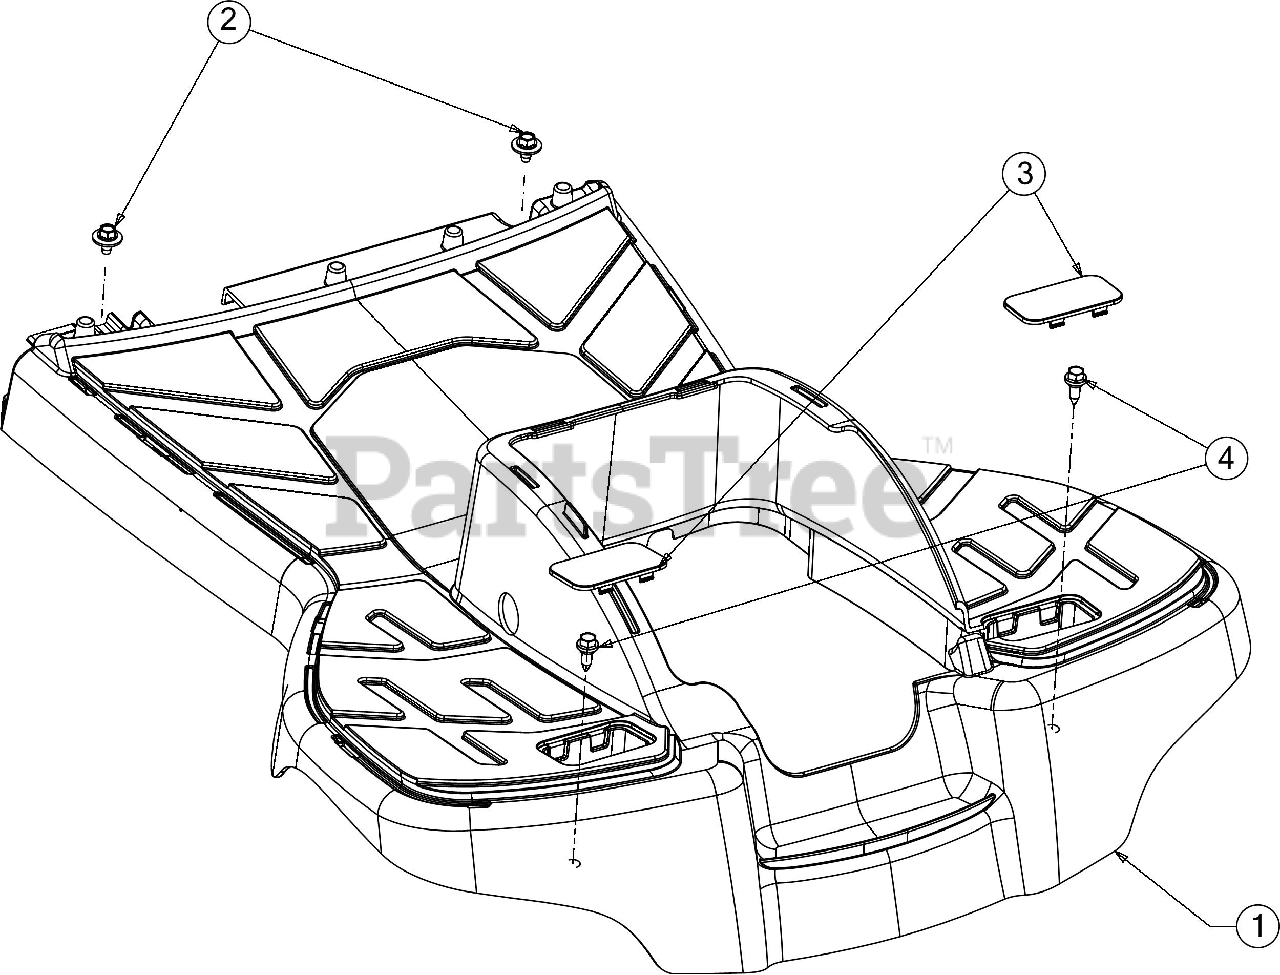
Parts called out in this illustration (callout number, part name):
1	RUNNINGBOARD W/RMC
1	RUNNING BOARD
2	SCREW 1/4-20 x .50
3	RUNNING BOARD PLUG
4	SHOULDER SCREW
